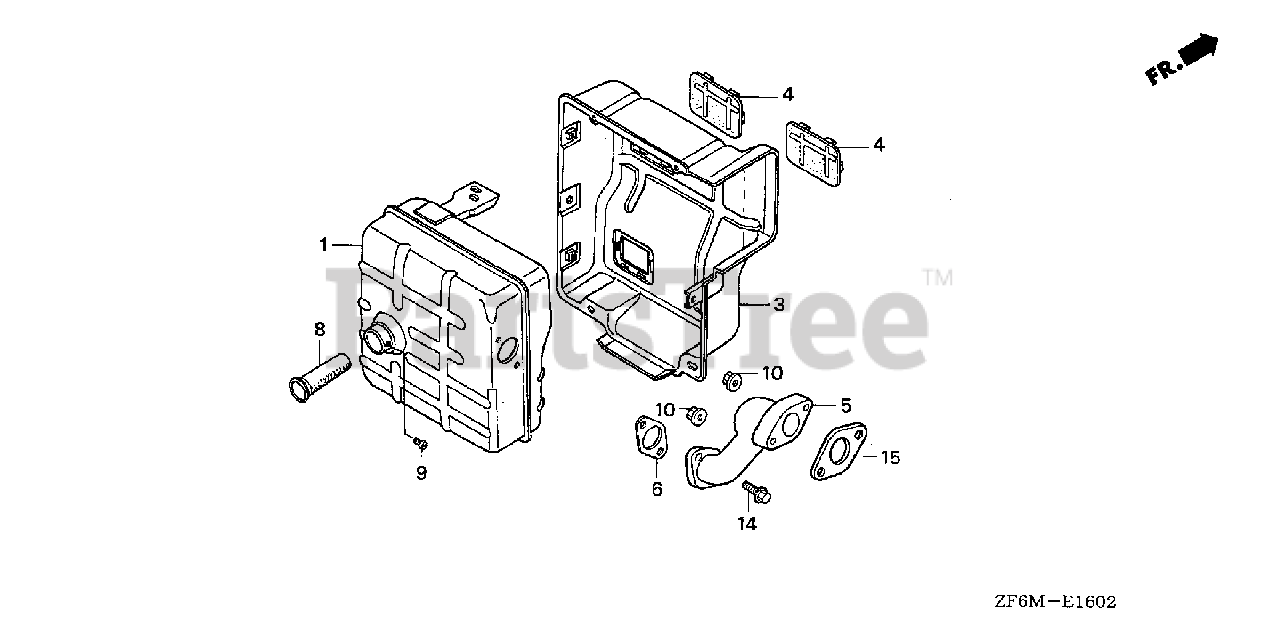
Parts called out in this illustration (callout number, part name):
1	MUFFLER (TSURUMI)
3	PROTECTOR, MUFFLER (INNER)
4	SEAL, MUFFLER PROTECTOR
5	PIPE, EX.
6	GASKET, EX. PIPE
8	ARRESTER, SPARK
9	SCREW, TAPPING (4X8)
10	NUT, FLANGE (8MM)
14	BOLT, FLANGE (8X20)
15	GASKET, EX. PIPE
15	GASKET, EX. PIPE (WACKER)
